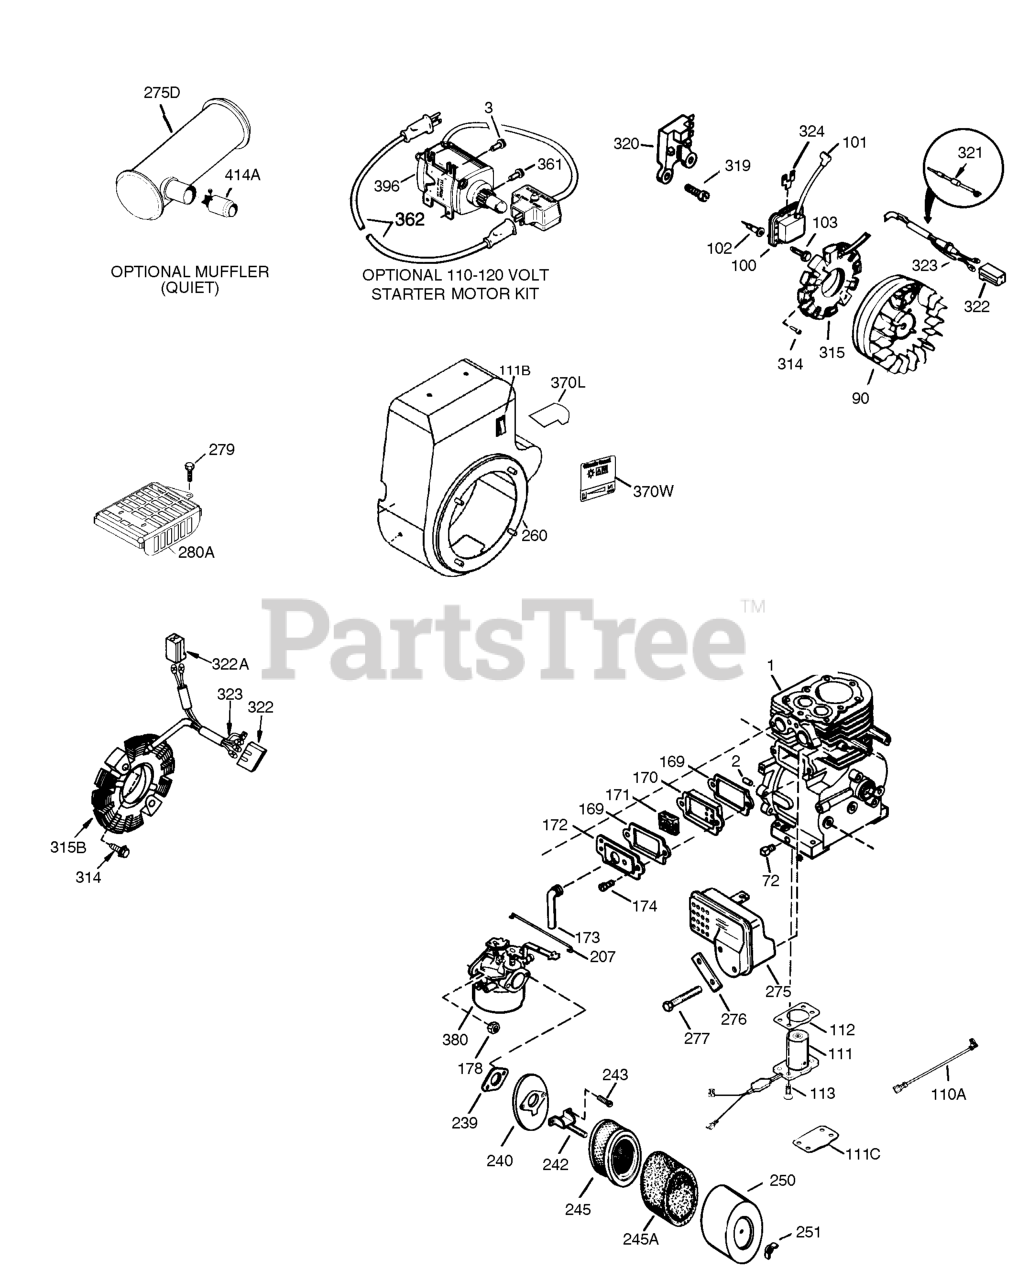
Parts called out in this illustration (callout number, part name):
1	CYLINDER
90	FLYWHEEL
100	LAMINATION
101	PLUG COVER
102	STUD
103	SCREW
110A	GROUND WIRE N/A
131A	SCREW
170	BREATHER
171	ELEMENT
172	VALVE COVER
186	GOV LINK
207	GOV LINK
260	BLOWER HSG
276	LOCK PLATE
315	ALT COIL
322	CONNECTOR
323	TERMINAL
380	CARBURETOR
